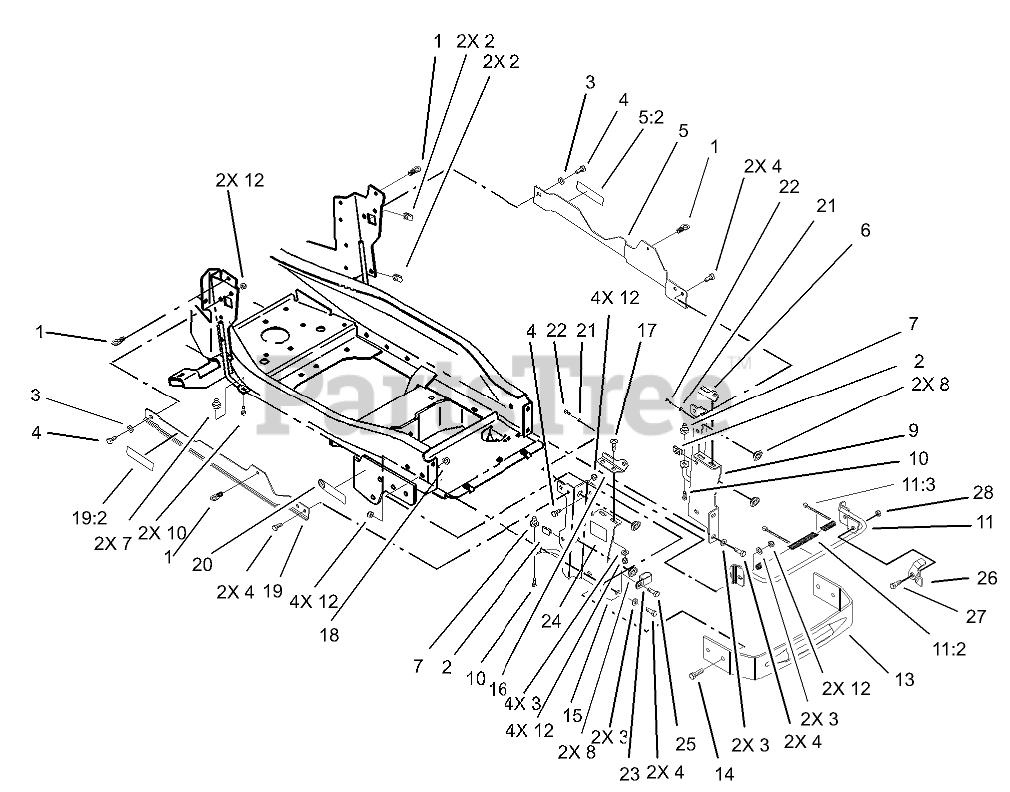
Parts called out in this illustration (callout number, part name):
1	LATCH ASM
3	WASHER-PLAIN
4	SCREW-HH
5	SUPPORT ASM
5:2	DECAL - WARNING
6	BRACKET-HINGE, LOWER LH
7	MOUNT-SIDEPANEL
8	GROMMET
9	SUPPORT-HOOD, LH
10	SCREW-PLASTITE
11	SUPPORT-HOOD
11:2	COVER-BRACE
11:3	TIE-CABLE
12	NUT-LOCK, NI
13	BUMPER-FRAME
14	SCREW-HH
15	SUPPORT-HOOD, RH
16	BRACKET-HINGE, LOWER RH
17	SCREW-CARR
18	NUT-LOCK, NI
19	SUPPORT ASM
19:2	DECAL - WARNING
20	DECAL-ATTACH A-MATIC
21	WASHER-FLAT
22	SCREW-THD FORM, HWH
23	CLAMP-TUBE
24	DECAL-SURFACE, HOT
25	SCREW-HH
26	LEVER-PROP, HOOD
27	BOLT-SHOULDER
28	NUT-LOCK, NI
